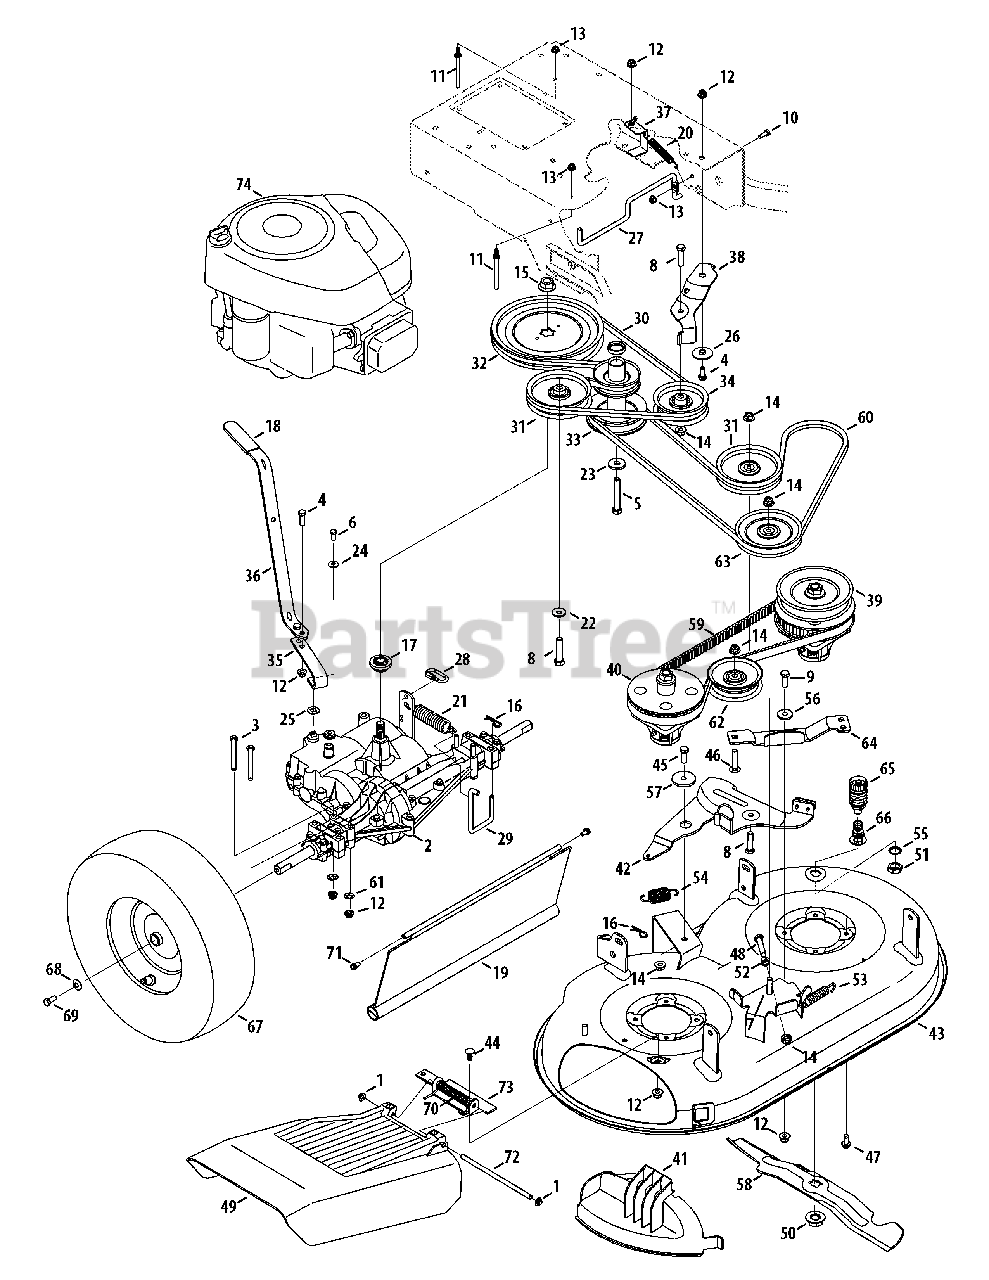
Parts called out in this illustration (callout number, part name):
1	Push Cap
2	Transmission 4-Speed
3	Screw, HH Cap, 5/16-18 x 2.75"
4	Screw, HH Cap, 5/16-18 x 1.00"
5	Screw, HH Cap, 7/16-20 x 2.75"
6	Screw, HH Cap, 1/4-28 x .625"
7	Screw, HH Cap, 3/8-16 x 1.50"
8	Screw, HH Cap, 3/8-16 x 1.75"
9	Screw, HH Cap, 3/8-16 x 1.25"
10	Screw, HH Cap, 1/4-20 x .75"
11	Belt Keeper
12	Nut, Flange Lock, 5/16-18
13	Nut, Flange Lock, 1/4-20
14	Nut, Flange Lock, 3/8-16
15	Nut, Flange, 9/16-18
16	Hairpin Clip, 092" x 1.64" Long
17	Pulley Hub
19	Trailing Shield
20	Extension Spring
21	Extension Spring
22	Washer, Spring, .401" x .870" x .063"
23	Washer, Flat, 450" x 1.250" x .164"
24	Washer, Bell
25	Washer, Flat, .39" x .87" x .06"
26	Spacer, Shoulder, .50" x .1475"
27	Belt Keeper Rod
28	Tri-Link Coupling
29	Trans Mount Rod
30	Belt, V Type
31	Idler Pulley, 4.25" Dia.
32	Flat Sheave 7.75"
33	Engine Pulley 3.20" x 4.35" Dia.
34	Idler Pulley 3.50" Dia.
35	Shift Rod, Lower
36	Shift Rod, Upper
39	Drive Spindle Assembly
40	Spacer Spindle Assembly
41	Mulch Plug
42	Idler Arm Assembly
43	Deck Assembly, 33-inch
44	Bolt, Carriage, 5/16-18 x .75"
45	Screw, HH Cap, 3/8-16 x 1.00"
46	Screw, Carriage, 3/8-16 x 1.75"
47	Screw, TT, 5/16-18 x .750"
48	Screw, HH Cap, 3/8-16 x 2.00"
49	Chute Deflector Assy (incl. ref. 72-76)
50	Nut, Flange, 5/8-18
51	Nut, Hex
52	Nut, Hex 3/8-16
53	Extension Spring, Timing Belt Tension
54	Extension Spring, Deck Brake
55	Washer, Lock
56	Spacer, Shoulder, .625" x .169"
57	Spacer, Shoulder, .884" x .190"
58	Blade, 17.9"
59	Belt, Timing
60	Belt, V Type
61	Push Nut
62	Idler Pulley, 3.50"
63	Idler Pulley, V-Type, 5.0"
64	Idler Timing Bracket
65	Water Nozzle Adapter
66	Water Nozzle
67	Wheel, 16 x 4 x 8
68	Washer, Bell, .340" x .872" x .060"
69	Screw, HH Cap, 5/16-24 x .75"
70	Deflector Torsion Spring
71	Screw, AB, 1/4-14 x .625"
72	Deflector Pin
73	Deflector Hinge Bracket
74	Replacement Engine 219807-3712-G5
